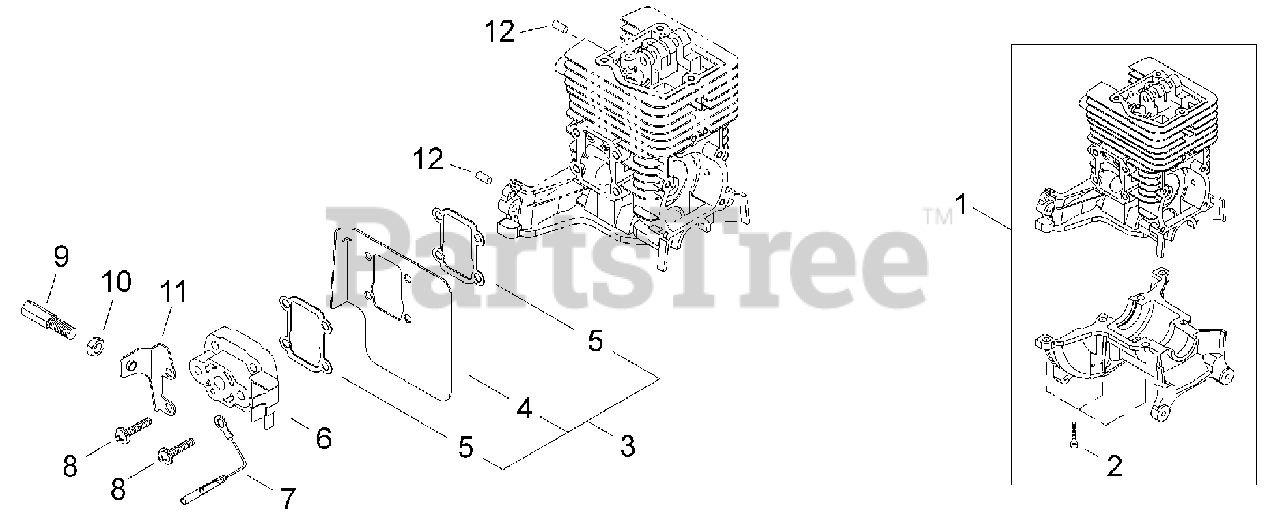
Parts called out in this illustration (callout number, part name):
1	CYLINDER & CRANKCASE ASSY
2	BOLT 5×16
3	SHIELD ASSY, INTAKE HEAT
4	HEAT SHIELD, INTAKE
5	GASKET, EXHAUST
6	INSULATOR WITH REED VALVE
7	LEAD - GROUND L= 110 MM
8	SCREW M5×22
9	ADJUSTER, THROTTLE CABLE
10	NUT, ADJUSTER LOCK M6
11	BRACKET, THROTTLE CABLE
12	PIN, LOCATING Ø4×8
